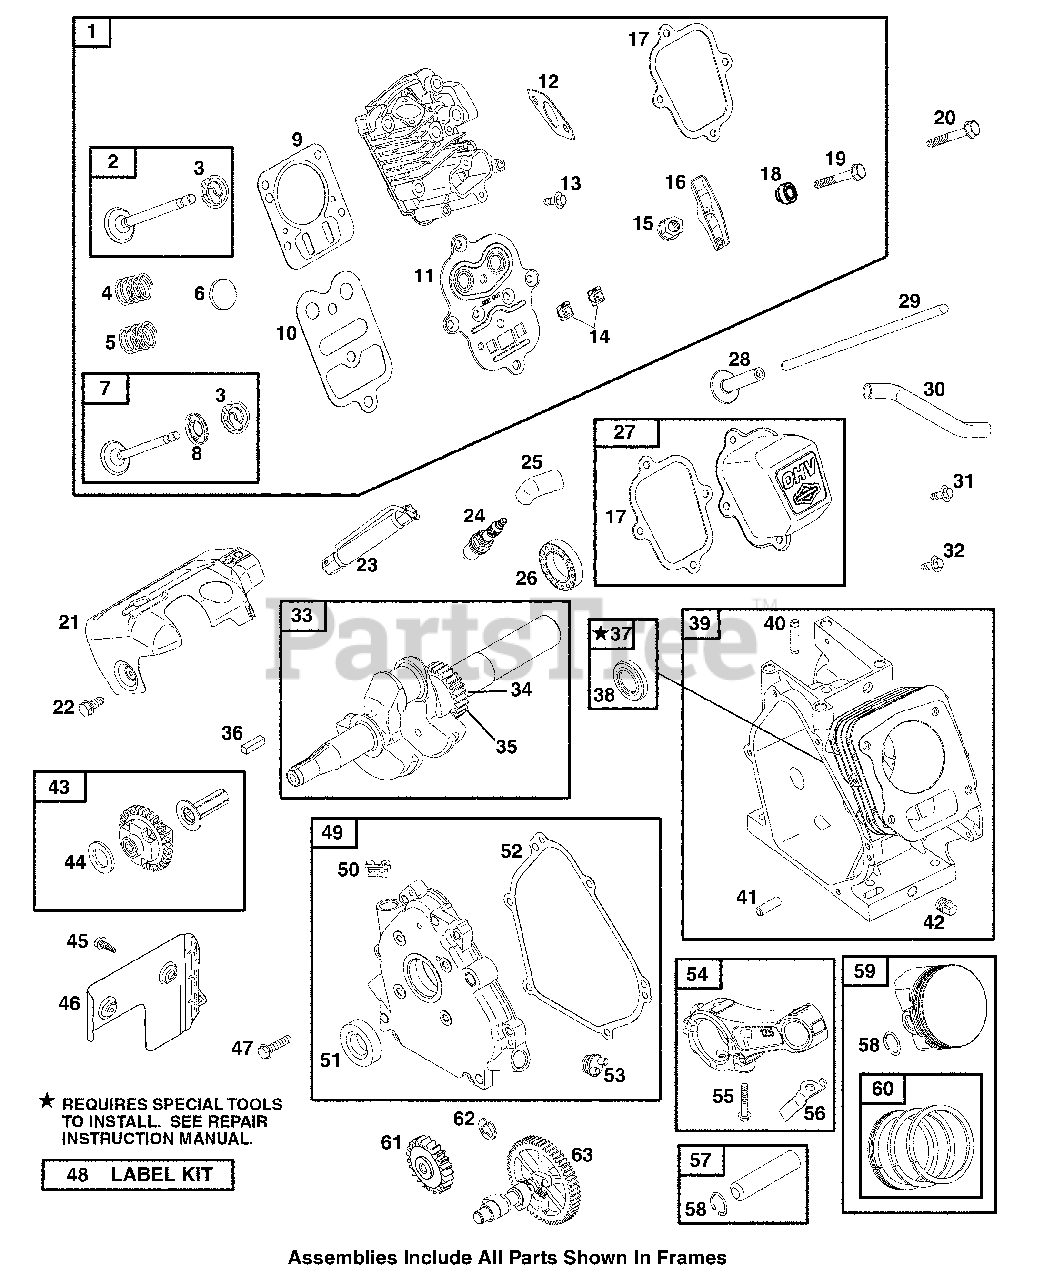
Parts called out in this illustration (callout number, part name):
1	Cylinder Head
2	Exhaust Valve
3	Valve Retainer
4	Valve Spring (Intake)
5	Valve Spring (Exhaust)
7	Intake Valve
8	Seal-Valve
9	Cylinder Head Gasket
10	Cylinder Head Plate Gasket
11	Cylinder Head Plate
12	Intake Gasket
13	Screw
14	Guide-Push Rod
15	Nut
16	Rocker Arm
17	Gasket-Rocker Cover
18	Rocker Arm Ball
19	Screw
20	Screw
21	Shield-Cylinder
22	Screw
23	Wrench-Spark Plug
25	Boot-Spark Plug
26	Ball Bearing
27	Cover-Rocker
28	Valve Tappet
30	Breather Tube
31	Screw
32	Screw
33	Crankshaft
34	Timing Key
35	Gear-Timing
36	Flywheel Key
37	Bushing/Seal Kit
38	Oil Seal
39	Cylinder Assembly
40	Bushing-Governor Crank
41	Pin-Locating
42	Oil Drain Plug
43	Governor Gear
44	Washer
45	Screw
47	Screw
49	Cover-Crankcase
52	Crankcase Gasket
53	Oil Fill Cap
54	Connecting Rod
55	Screw
56	Connecting Rod Dipper
57	Piston Pin
58	Piston Pin Lock
59	Piston Assembly (Standard)
60	Ring Set (Standard)
61	Gear-Idler
62	Ring-Retaining
